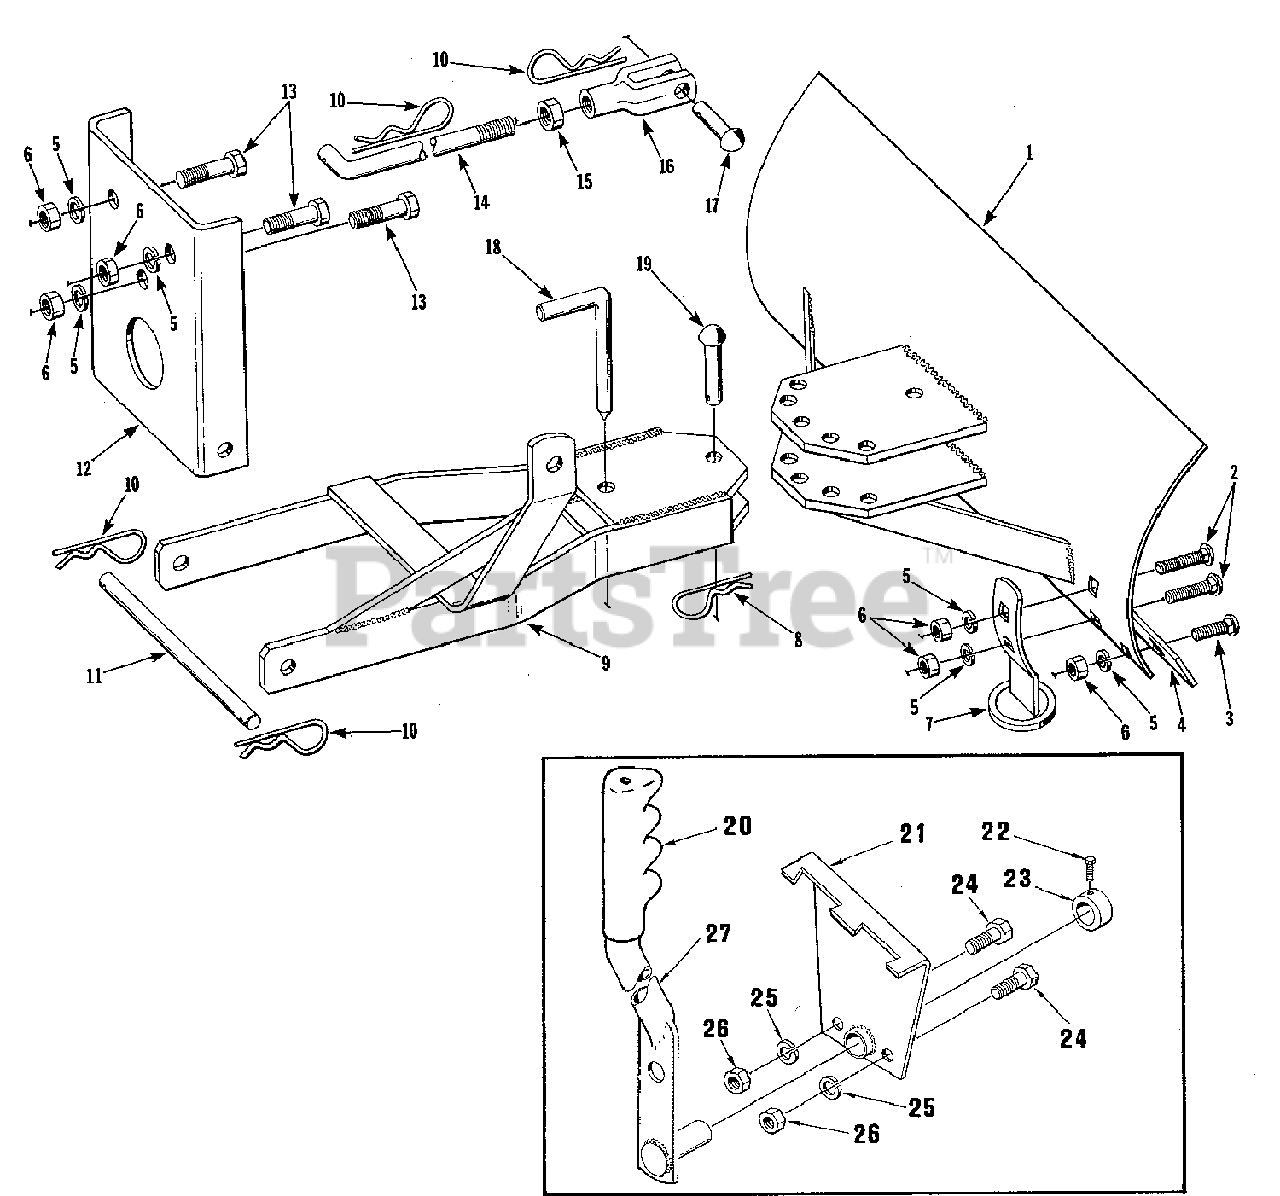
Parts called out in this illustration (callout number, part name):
1	BLADE ASSEMBLY, 36"
2	BOLT, Carriage, 3/8-16 x 1
3	BOLT, Carriage, 3/8-16 x 3/4
5	WASHER, Lock, 3/8
6	NUT, Hex, 3/8-16
7	SHOE ASSEMBLY
9	BAR ASSEMBLY, Push
12	SUPPORT, Front Blade
13	SCREW, Cap, 3/8-16 x 2-3/4
15	NUT, Hex Jam, 1/2-20
16	YOKE, Rod End Adjacent, 1/2-20
17	PIN, Yoke, 1/2
20	GRIP, Handle
21	QUADRANT, Lift
22	SCREW, Set, 5/16-18 x 5/16
24	SCREW, Cap, 5/16-18 x 5/8
25	WASHER, Lock, 5/16
26	NUT, Hex, 5/16
